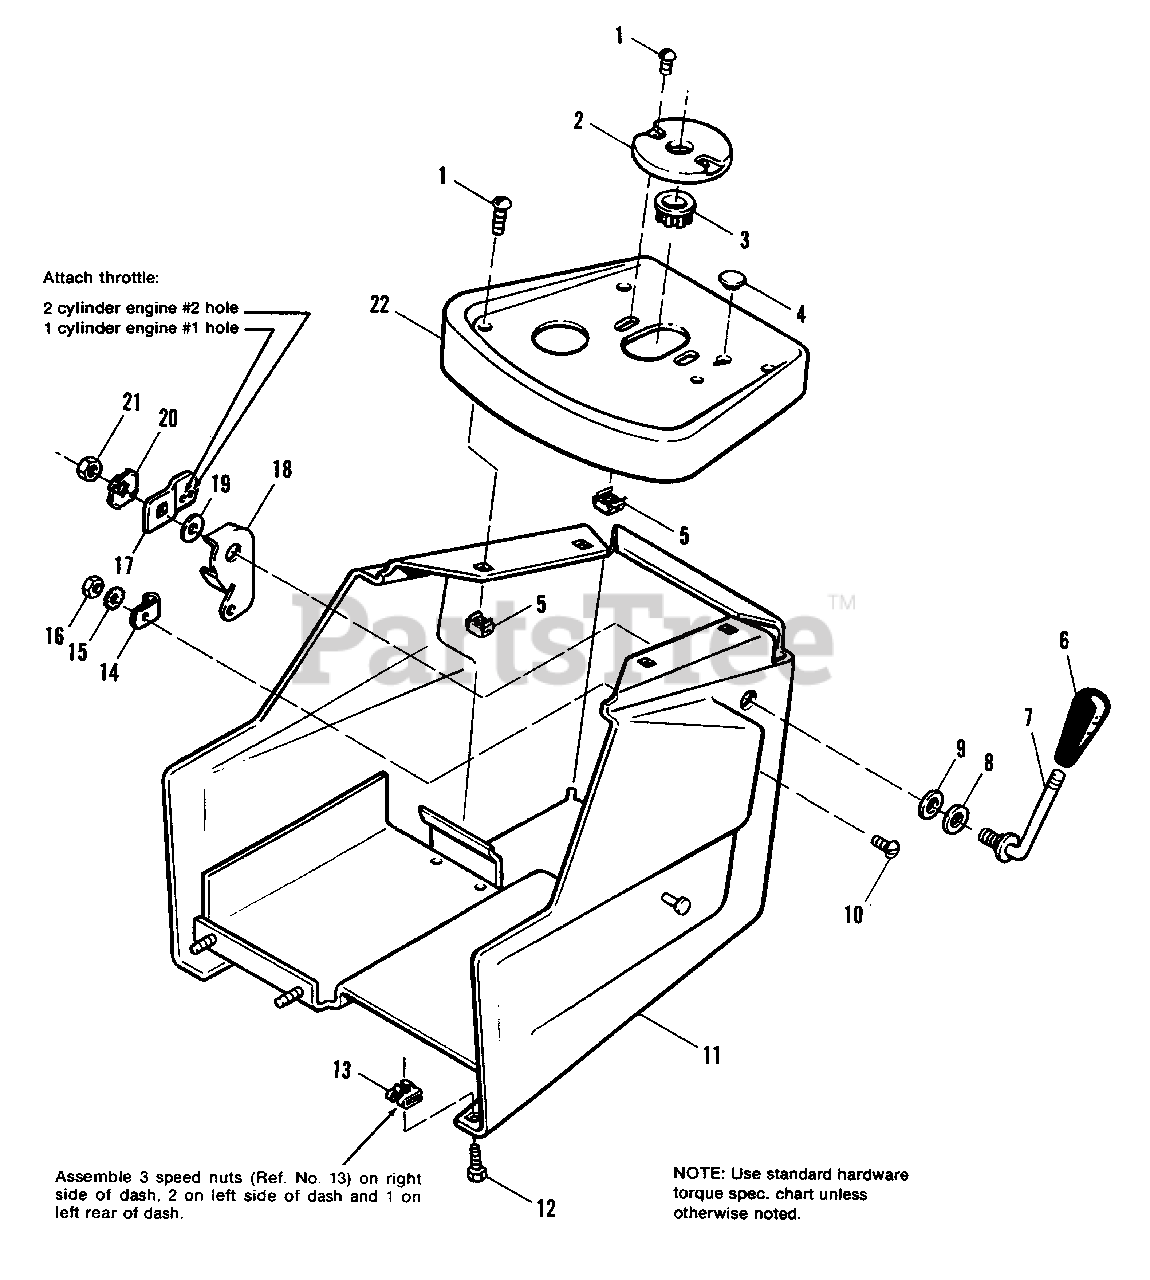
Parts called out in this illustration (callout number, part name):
1	SCREW, Machine, Rd. Hd., 1/4-20 x 1/2
2	PLATE, Adjusting, Steering
4	PLUG, Button
5	NUT, Tinnerman
6	KNOB
7	HANDLE, Clutch Control
10	SCREW, Round Hd., #10-32 x 1/2
12	SCREW, Hex, Self Tapping, #14AB x 3/4
13	NUT, Speed
14	CLIP, Bowden Wire
15	LOCKWASHER, Ext., #10
16	NUT, Machine, Hex, #10-32
17	ARM, Throttle
18	STOP, Throttle
20	LOCKWASHER, Dished Type, 3/8
21	LOCKNUT, Hex, 3/8-16
22	PANEL, Instrument
